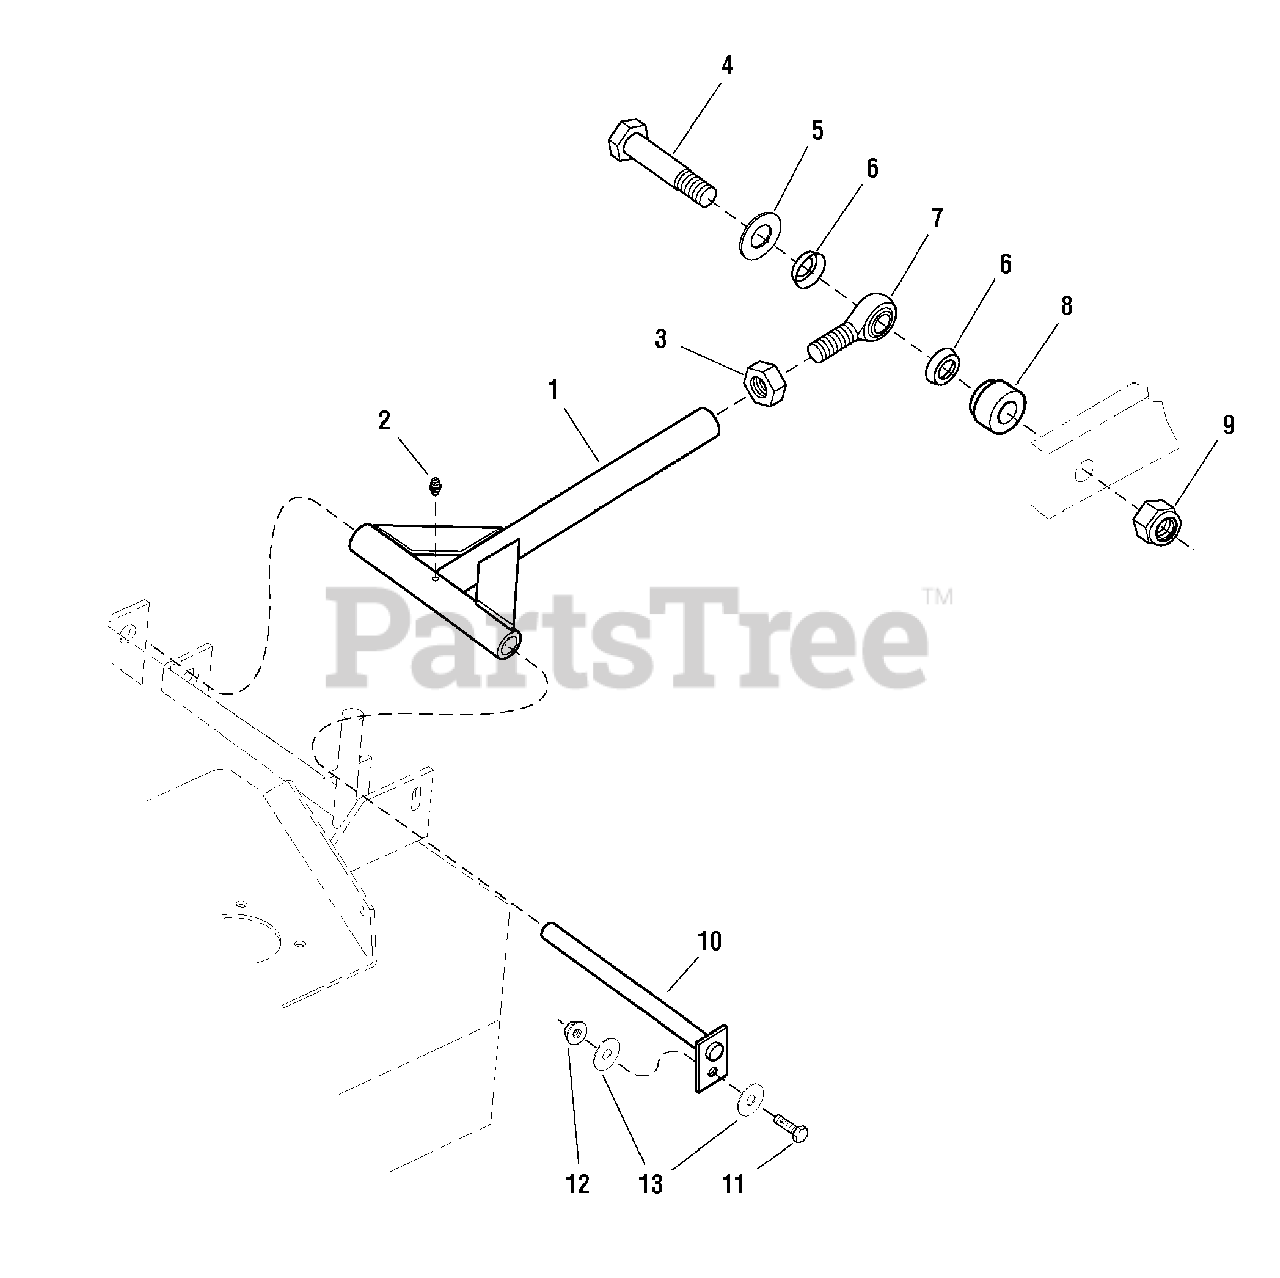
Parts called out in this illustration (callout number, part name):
1	PUSHER BAR ASSEMBLY
2	GREASE FITTING
3	NUT, Hex, Jam, 3/4-16
4	CAPSCREW, Hex Hd, 3/4-16 x 4
5	WASHER, 3/4
6	ROD END SEAL
7	BALL JOINT, 3/4-16
8	SPACER, .75 x 1.50 x 1.00
9	NUT, Hex, Nylon Lock, 3/4-16
10	WELD, DECK MOUNT SHAF
11	CAPSCREW, Hex Hd, 3/8-16 x 1-1/4
12	NUT, Hex, Nylon Lock, 3/8-16
13	WASHER, 3/8
